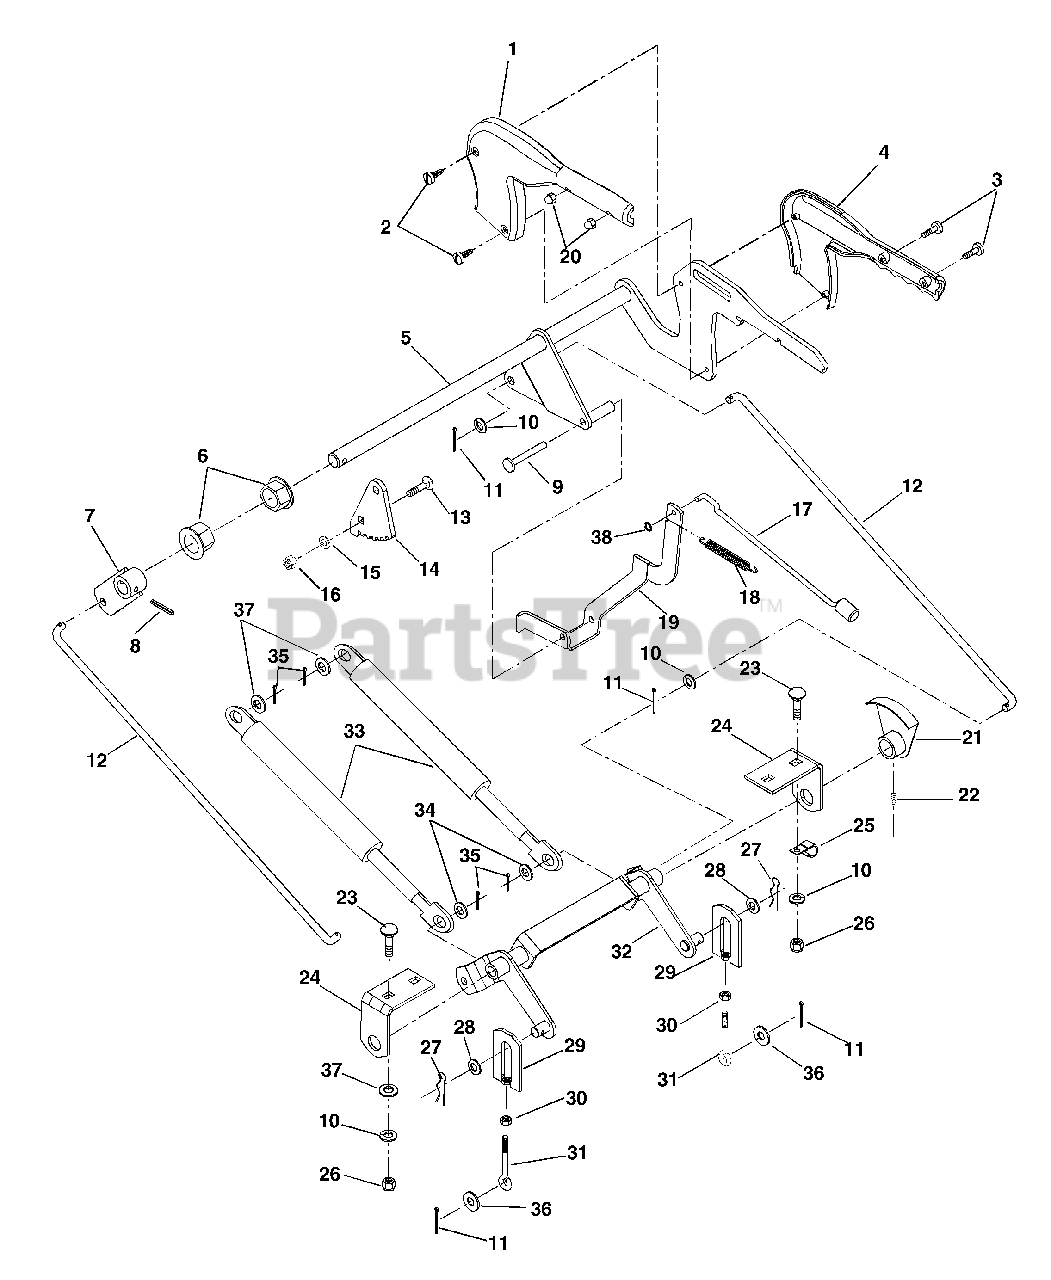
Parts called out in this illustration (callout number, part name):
1	COVER - LIFT RH
2	SCR-TAP 10-16X1.125HI-LOTPHBL
3	SCR-MCH 10-24X.62 P/HD
4	COVER - LIFT LH
5	LEVER, LIFT
6	BSHG-FLG .750X.873HEXX.53X1.18
7	ARM, LIFT
8	PIN-GRV .250X1.25 TP A
9	PIN, PIVOT .312 X 2.56
10	@WSHR-LK .38X.094 REG YWZC
11	@PIN-CTR .12X1.00 EXTPRSQCT YZ
12	LINK, LIFT
13	@BLT-RDHDSQNK .31-18X.75 G5YZ
14	QUADRANT, LIFT
15	WSHR-FL-STL .323X.625X.062 YWZ
16	@NUT-LK-CTR .31-18 YWZC
17	PIN - LIFT
18	SG-TENS .048X.44X2.25 WLD 9
19	LEVER, DETENT
20	NUT,10-24 LOW CROWN, ACORN
21	INDICATOR, DECK HEIGHT
22	SCR-SET .25-20X.25 SKHCUP OH
23	BLT-RHHDSQSHNK .38-16X.75 G2YZ
24	BRACKET, CENTER LIFT
25	J-CLAMP
26	@NUT-HEX .38-16 YWZC
27	PIN-HAIR-EXT .12X.31X2.37 YWZC
28	@WSHR-FL-STL.531X1.06X.095YWZC
29	LINK, ADJUSTMENT
30	NUT-HEX-JAM .375-16 YWZC
31	BLT-EYE .375-16X2.50 YWZC
32	LEVER, CENTER LIFT
33	SG-GAS COMP .315X.75X10.00 120
34	@WSHR-FL-STL.38X.875X.083 YWZC
35	@PIN-CTR .12X.75 EXTPRSQCT YWZ
36	@WSHR-FL-STL.656X1.31X.095 YWZ
37	@WSHR-FL-STL.406X.812X.065 YWZ
38	RG-RTNG-EXT .250X.010
